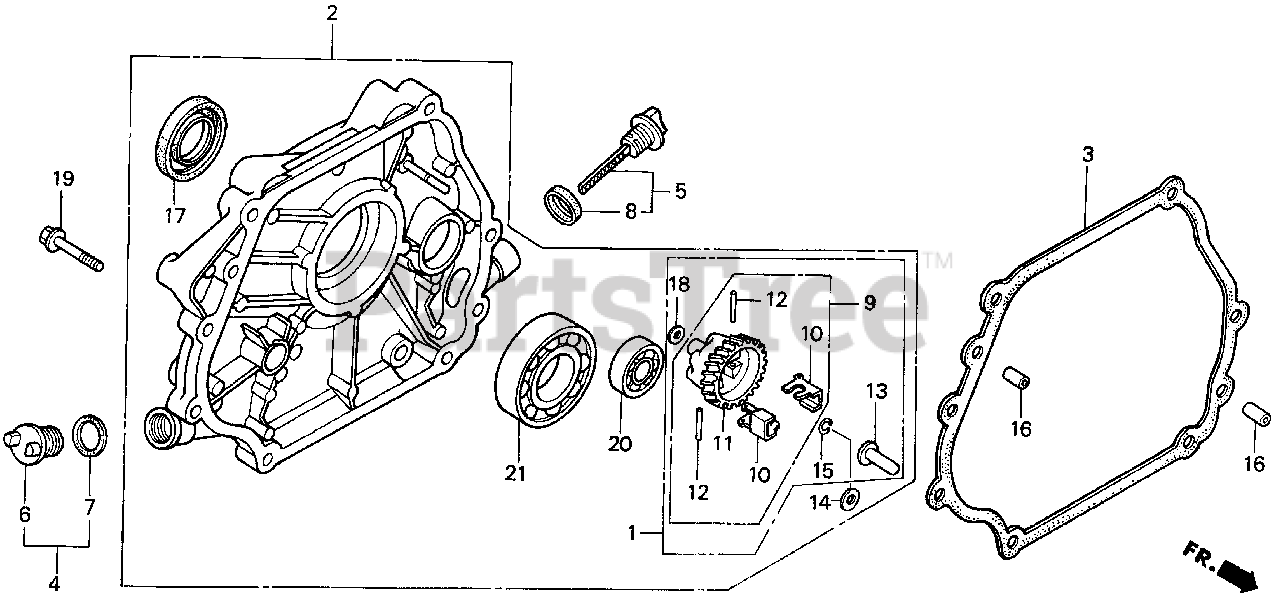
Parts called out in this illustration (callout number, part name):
1	GOVERNOR KIT (BALANCER)
2	COVER ASSY., CRANKCASE (S-TYPE)(BALANCER)
3	GASKET, CASE COVER
5	CAP ASSY., OIL FILLER
6	CAP, OIL FILLER
7	GASKET, OIL FILLER CAP
8	GASKET, OIL FILLER CAP
9	GOVERNOR ASSY. (BALANCER)
10	WEIGHT, GOVERNOR
11	HOLDER, GOVERNOR WEIGHT
12	PIN, GOVERNOR WEIGHT
13	SLIDER, GOVERNOR
14	WASHER (6X16)
15	CLIP, GOVERNOR HOLDER
16	PIN, DOWEL (8X12)
17	OIL SEAL (30X46X8)
18	WASHER, PLAIN (6MM)
19	BOLT, FLANGE (8X35)
20	BEARING, RADIAL BALL (6202)
21	BEARING, RADIAL BALL (6206)
